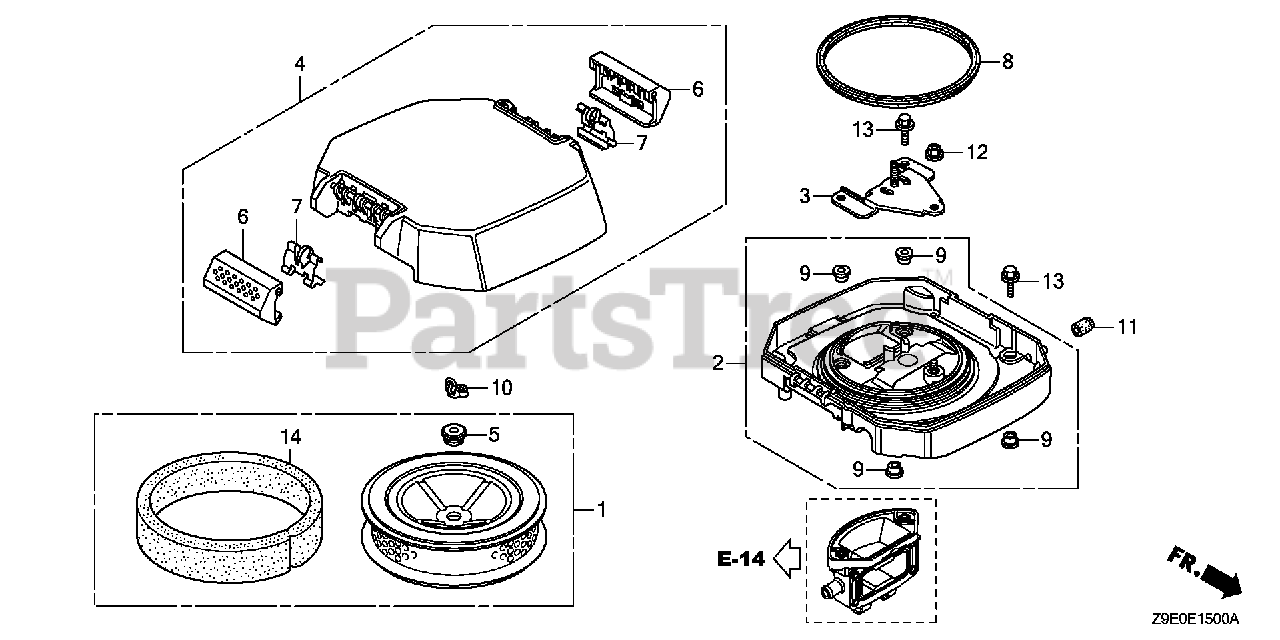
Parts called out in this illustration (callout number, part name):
1	ELEMENT, AIR CLEANER
2	HOUSING, AIR CLEANER
3	STAY, AIR CLEANER ELEMENT
4	COVER, AIR CLEANER
5	GROMMET, AIR CLEANER
6	KNOB, AIR CLEANER COVER
7	SPRING, AIR CLEANER HOUSING COVER
8	GASKET, AIR CLEANER HOUSING
9	COLLAR, FAN COVER
10	NUT, TOOL BOX SETTING
11	CAP, SEALING
12	NUT, FLANGE (6MM)
13	BOLT, FLANGE (6X18)
14	FILTER (OUTER)
